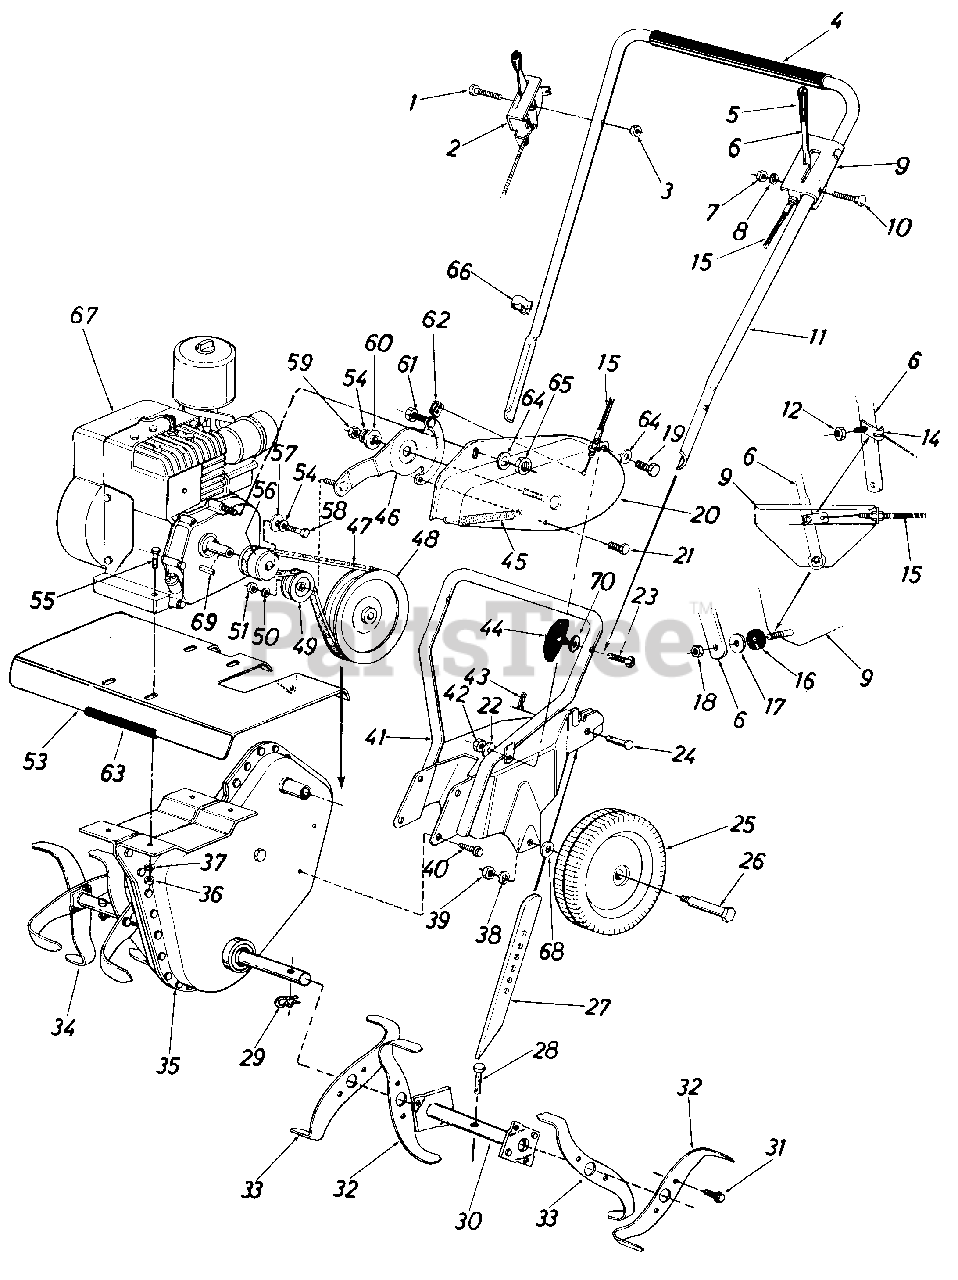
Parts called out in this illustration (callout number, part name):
1	Hex Bolt 1/4-20 x 1.50" Lg.*
2	Throttle Control Ass'y. Com p.
3	Hex Cent. L-Nut 1/4-20 Thd.
4	Grip-14" Lg.
5	Handle Grip
6	Clutch Handle Ass'y.
7	Hex Cent. L-Nut 1/4-20 Thd.
8	Fl-Wash. 1/4" I.D. x .50" O.D. x .063
9	Clutch Handle Brkt. Ass'y.
10	Carr. Bolt 1/4-20 x 1.25" Lg.*
11	Upper Handle
12	Hex Cent. L-Nut 1/4-20 Thd.
15	Clutch Cable
16	Rubber Wash.
17	Fl-Wash. 1/4" I.D. x .75" O.D. x .063
18	Hex Cent. L-Nut 1/4-20 Thd.
19	Hex Bolt 1/4-20 x .75" Lg.*
20	Belt Cover Ass'y.
21	Hex Wash. Hd. Tap Scr. 1/4 X .50
22	L-Wash. 1/4" I.D.*
23	Curved Hd. Bolt 5/16-18 x 1.75" Lg.
24	Clevis Pin
25	Wheel Ass'y.-7"
26	Shoulder Bolt
27	Depth Bar
28	Clevis Pin .31 Dia x 1.50" Lg.
29	Hairpin Cotter
34	Tine Ass'y. Comp.
35	Chain Case Ass'y. Comp.
36	Hex Nut 5/16-18 Thd.*
37	L-Wash. 5/16" Scr.*
38	L-Wash. 3/8" Scr. H.D.
39	Hex Cent. L-Nut 3/8-16 Thd.
40	Hex Wash. SF-Tap Scr. 5/16-18 x .50" Lg.
43	Intern. Cotter Pin
44	Hand Knob
45	Extension Spring .60 O.D. x 4.88" Lg.
46	Idler Arm Ass'y.
47	Belt 3/8" x 29" Lg.
48	Chain Case Pulley 5 1/2 x 1/2"
49	Fl-ldler 2"
50	L-Wash. 5/16" Scr.*
51	Hex Nut 3/8-24 Thd.*
55	Hex Bolt 5/16-18 x 1.50" Lg.
56	Engine Pulley 3/8 V x .7525 I.D. x 2" O.D.
57	Fl-Wash. .385 I.D. x 1.00" O.D. x.135
58	Hex Bolt 3/8-24 x 1.00" Lg.*
59	Hex Nut 5/16-18 Thd.*
60	Shld. Spacer.50" Dia. x .133
61	Hex Cent. L-Nut 1/4-20 Thd.
63	Trim Strip-4"
64	L-Wash. 1/4" I.D.*
65	Hex Cent. L-Nut 1/4-20 Thd.
66	Cable Tie
67	Engine
68	Bell-Wash.
69	Square Key 3/16 x 3/4" Lg.
70	Belleville Washer
